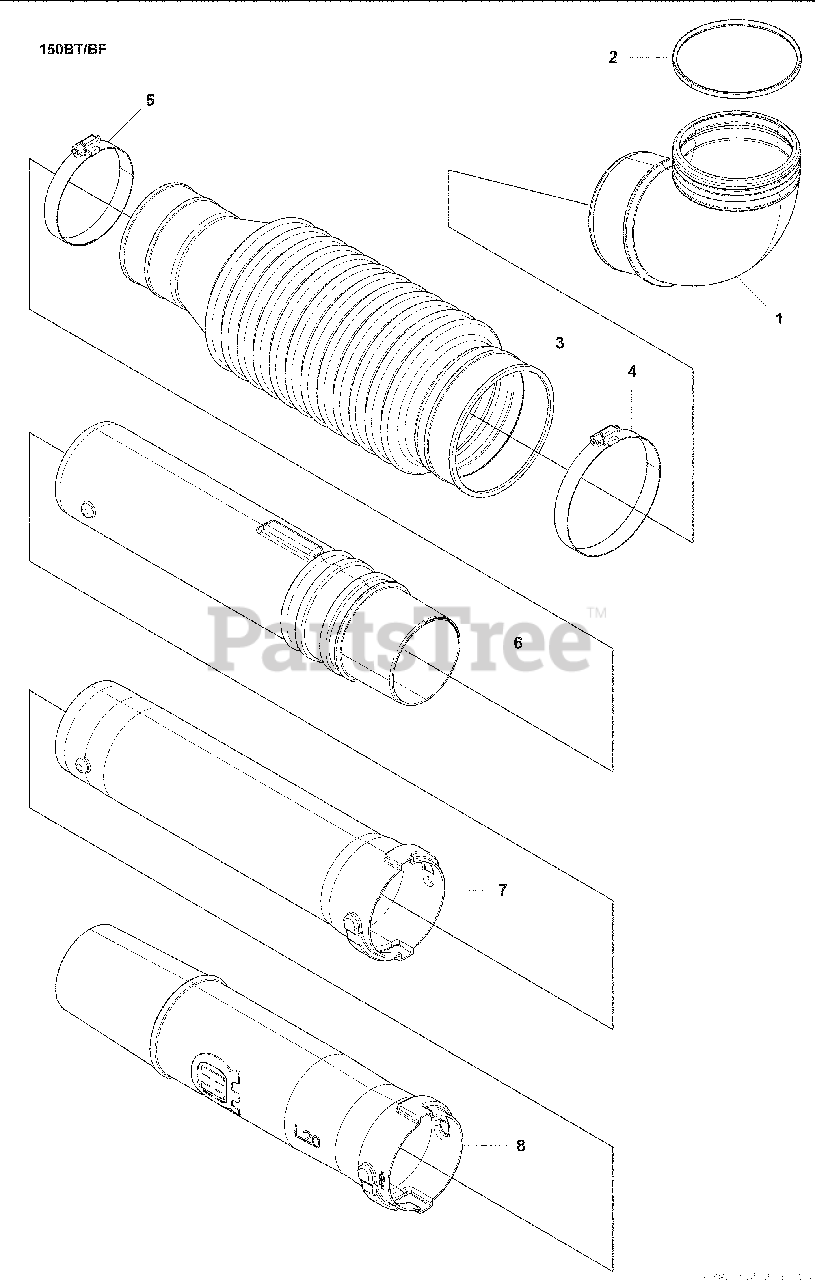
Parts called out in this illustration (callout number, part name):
1	Elbow Tube, T403031410
2	O-Ring
3	Flex Pipe
4	Clamp, F115
6	Swivel Joint Tube
7	Middle Tube
